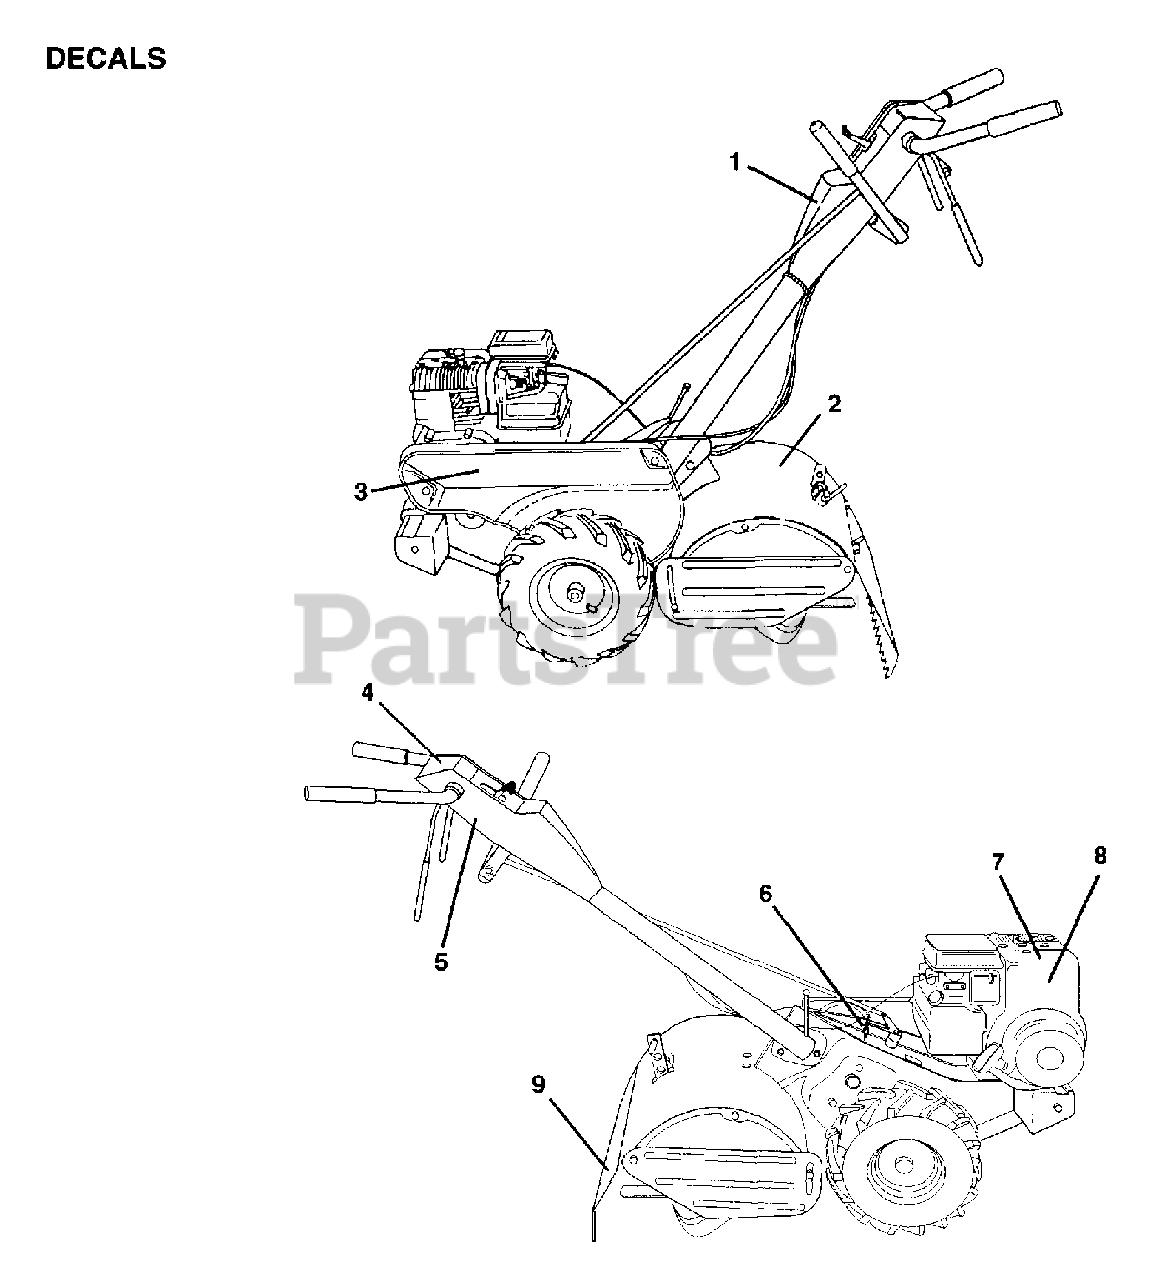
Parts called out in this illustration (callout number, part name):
1	DECAL.PNL.CNT.
2	DECAL.SHLD.TINE
3	DECAL.GD.BELT 3.5
4	DECAL.INSTRUCTION
5	DECAL TI
6	DECAL CRT
8	"DECAL,ENG HP"
9	DECAL TI
